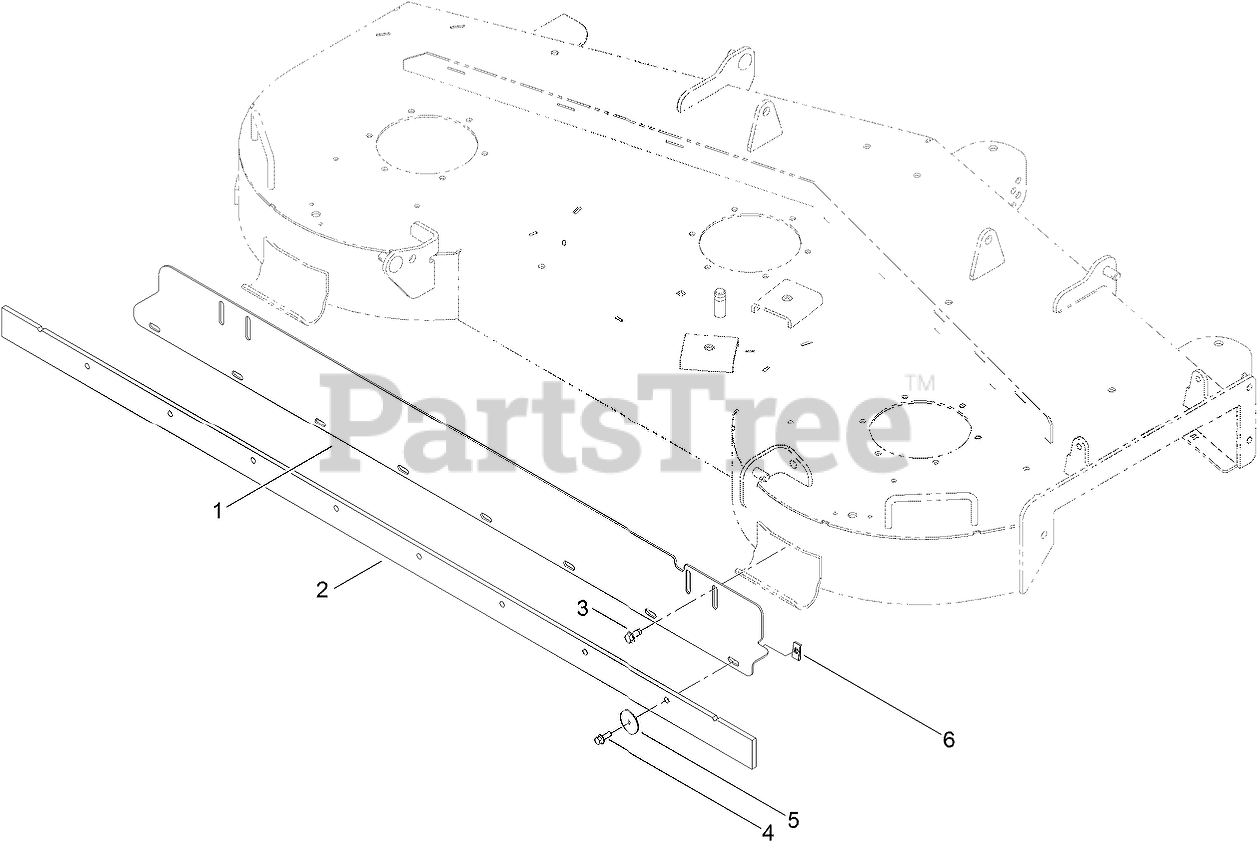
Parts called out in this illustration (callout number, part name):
3	SCREW-HWHTF
4	SCREW-HHF
5	WASHER-FENDER
6	NUT-SPEED
